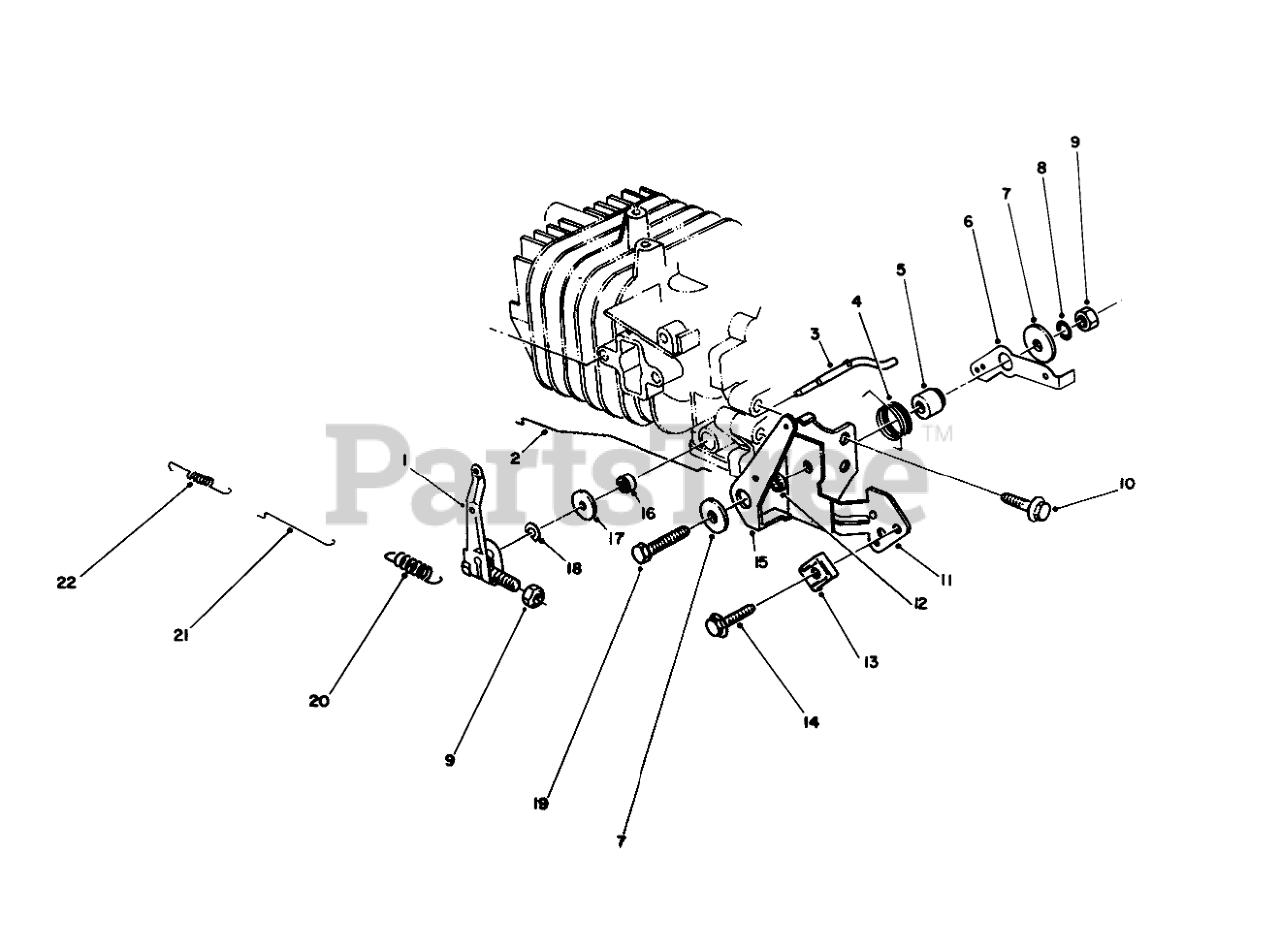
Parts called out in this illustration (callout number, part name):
1	ARM-GOVERNOR
2	ROD-CHOKE
3	Shaft-Govemor
4	SPRING-CHOKE LEVER
5	Gov Lever Spacer
6	LEVER-SPRING, GOVERNOR
7	WASHER
8	LOCKWASHER
11	BRACKET-THROTTLE, CONTROL
12	SPACER-CHOKE LEVER
13	CLAMP
15	LEVER-CONTROL, CHOKE
16	SEAL-OIL
17	WASHER
18	E-RING
20	SPRING-GOVERNOR
21	ROD-CARBURETOR
22	SPRING
